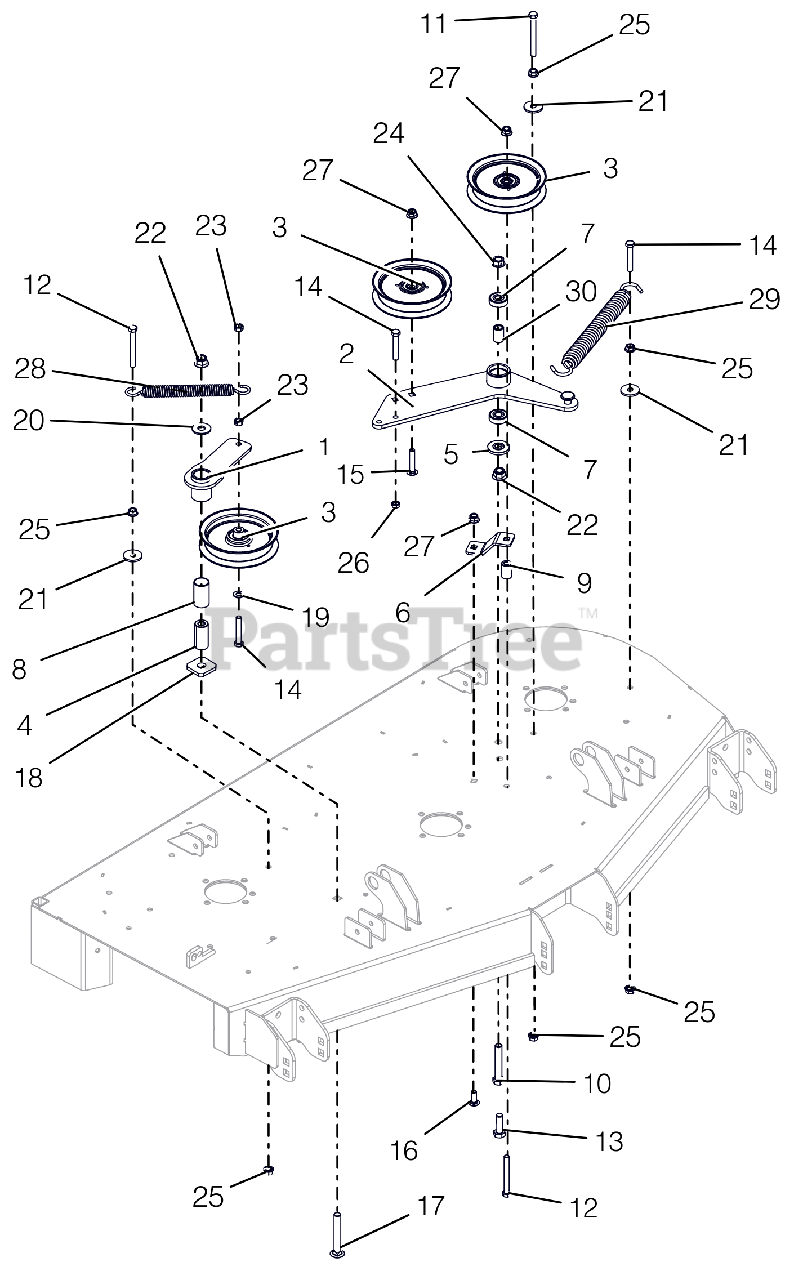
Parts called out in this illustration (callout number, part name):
1	WMT, IDLER ARM - BLACK
2	DECK PTO IDLER ARM WLDMT - BLK
3	IDLER, FLAT 5.00"
4	BSHG, SPCR .502X.997X2.03 PM
5	SPACER, IDLER ARM
6	PTO FIXED IDLER MTG BRKT-ORG
7	BRG-BALL .500X1.38X.437
8	BSHG, 1.00X1.125X1.937
9	BUSHING, SLV .380X.750X1.190
10	@BLT-HEX .50-13X3.00 GR5 YWZC
11	@BLT-HEX .38-16X3.50 GR5 YWZC
12	@BLT-HEX .38-16X3.25 GR5 YWZC
13	@BLT-HEX .50-13X1.50 GR5 YWZC
14	@BLT-HEX .38-16X2.25 GR5 YWZC
15	BLT-RDHDSQNK .38-16X2.00 SHTYW
16	@BLT-RDHDSHSQNK.38-16X1.0 G5YZ
17	@BLT-RDHDSQNK .50-13X3.50 G5YZ
18	WSHR-FLT .640X1.75X.250
19	@WSHR-FL-STL.406X.812X.065 YWZ
20	@WSHR-FL-STL.563X1.38X.109YWZC
21	WSHR-FL-STL .406X1.375X.135 YZ
22	@NUT-LK-NYL-FLG .50-13 YWZC
23	@NUT-LK-CTR .38-16 YWZC
24	NUT-LK-CTR-FLG .50-13 YWZC
25	@NUT-SPNLK-FLG .375-16 YWZC
26	NUT-HEX-JAM .375-16 YWZC
27	@NUT-LK-NYL-FLG .38-16 YWZC
28	SPRING, EXTENSION
29	SPRING, EXTENSION
30	SPACER .510 X .75 X 1.1485
